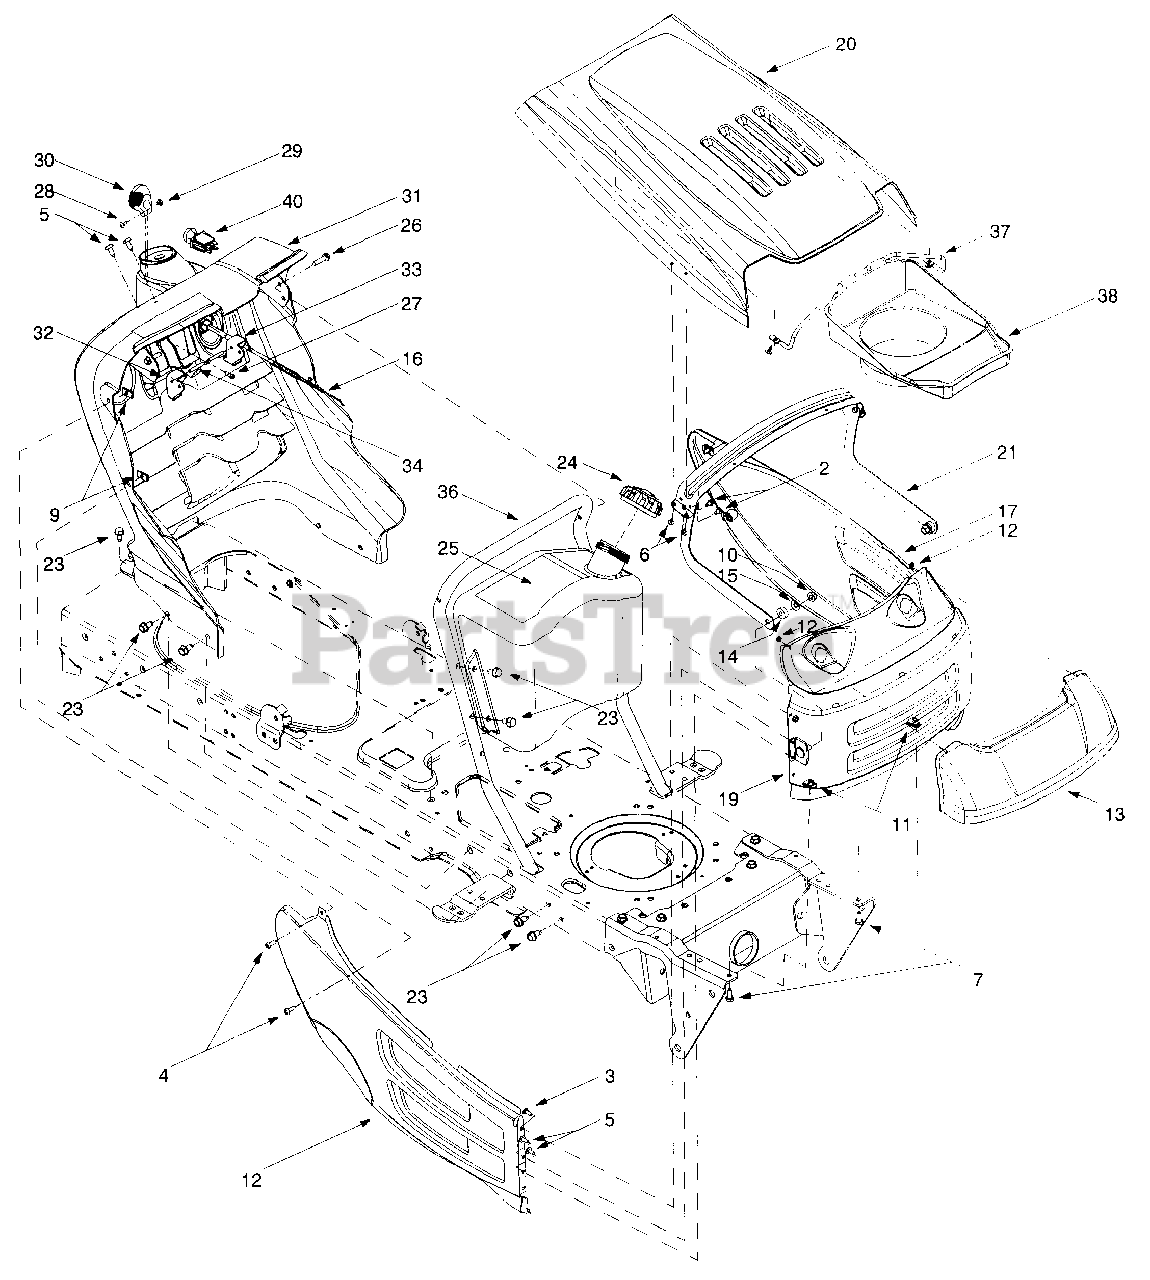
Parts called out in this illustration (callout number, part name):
2	Self-tapping Screw, 1/4-20 x .5
3	Hex Cap Screw, 1/4-20 x .62
4	Phillips Pan Screw, 1/4-20 x .75
5	Tap Screw, 1/4-20 x .625
6	Screw, #10-16 x .375
7	Hex Cap Screw, 5/16-18 x 1.25
9	U-type Speed Nut, 1/4-20
10	Flange Lock Nut, 3/8-16
11	U-nut, 5/16-18
12	Retainer Nut, 3/8
13	Headlight Lens (8-style)
14	Rubber Washer, .87 x .33
15	Bell Washer, .401 x .87 x .063
24	Fuel Cap
25	Fuel Tank (two gallon)
26	Screw, 1/4-20 x 1.25
27	Self-tapping Screw, 1/4-15 x .75
28	Truss Phillips Screw, #8-32 x .375
29	Hex Nut, #8-32
30	Throttle Control Knob
31	Dash Panel (8-style)
32	Cruise Control Button
33	Parking Brake Button
34	Flat Washer, 9/32 x 1/2 x 1/16
38	Heat Shield (8-style)
40	Electric PTO Switch
